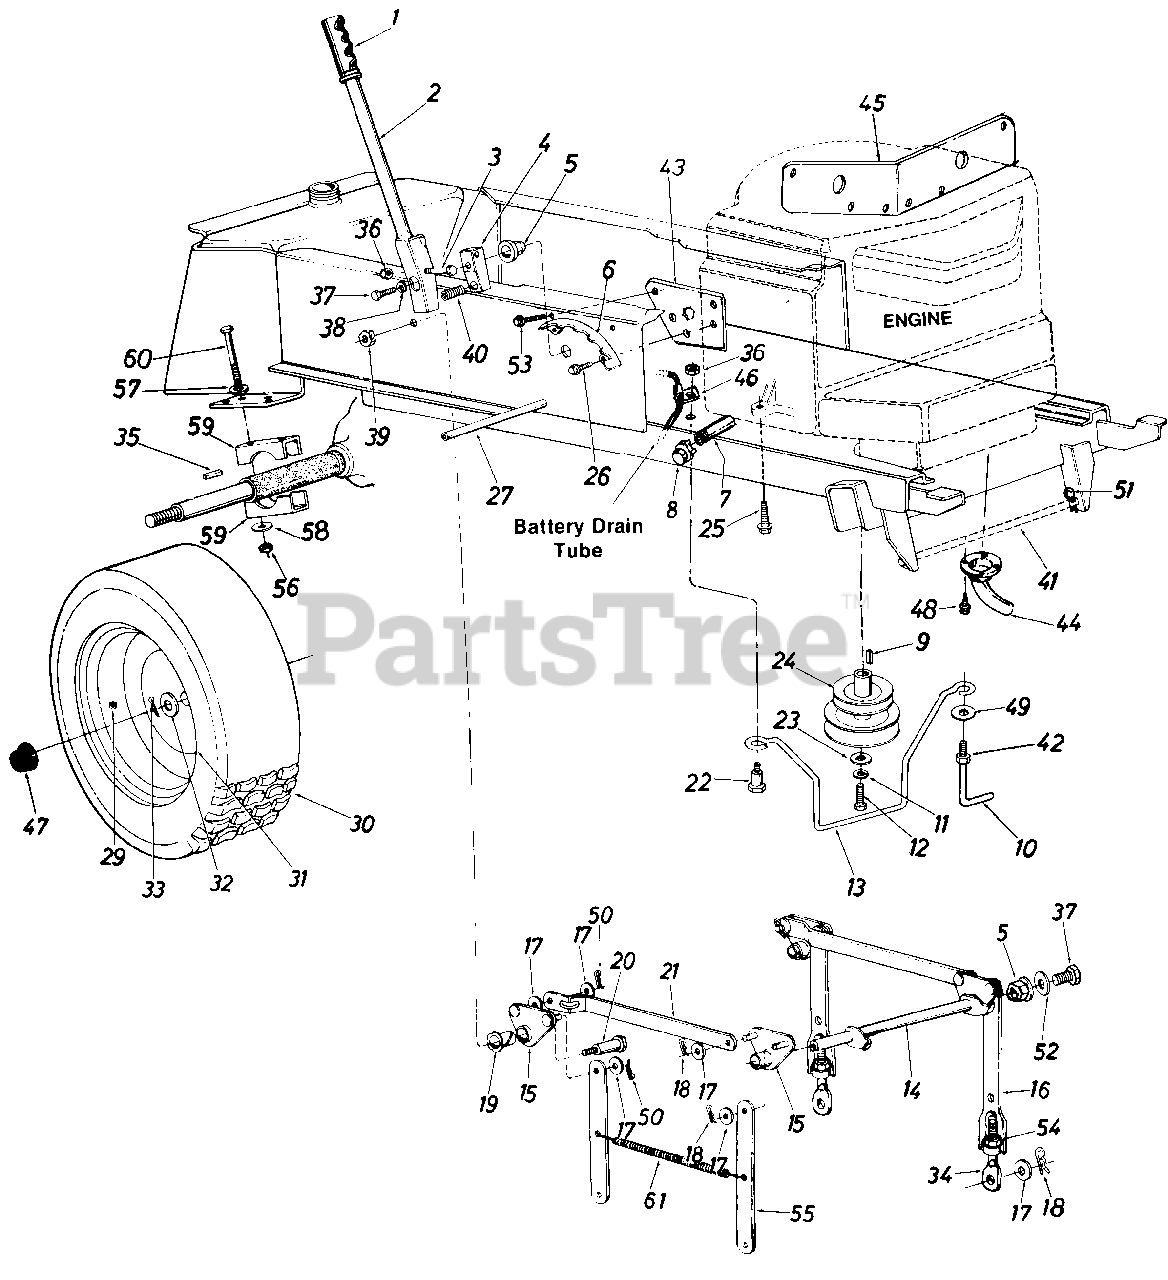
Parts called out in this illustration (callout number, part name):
1	Grip
2	Lift Handle Ass'y.
3	Hex Scr. 5/16-18 x 1.50" Lg.
4	Lift Shaft Drive
5	Plastic Hex Brg. 5/8" I.D.
8	Pipe Cap 3/8-18 Npt.
9	Sq. Key 1/4" x 1/4" x 1.50" Lg.
10	Belt Guard Lock Pin
11	L-Wash. 7/16" Scr.
12	Hex Scr. 7/16-20 x 1.50" Lg.
13	Belt Guard
14	Lift Shaft Ass'y.
15	Lift Pivot Brk't. Ass'y.
16	Adj. Deck Lift Link
17	Fl-Wash. 112" I.D. x 1.00" O.D. x .090
18	Hairpin Cotter
19	Nyliner 5/8" I.D. x .88" Lg.
20	Shld. Scr. 5/8" Dia. x .96" Lg. 3/8-16
23	Flat Wash. .44" I.D. x 1.25" O.D. x .17
24	Two-Step Engine Pulley 4 75 & 5.56
25	Hex Wash. Hd. Scr. 3/8-16 x 1.25" Lg.
26	Hex Thd. Rolling Scr. 5/16-24 x .75" Lg.
27	Running Board Rod
29	Air Valve
33	Cotter Pin 3/16" Dia. x 1.50" Lg.
34	Eye Bolt Adj. Link 1/2-13 Thd.
35	Sq. Key 1/4 x 3.0"
36	Hex Cent. L-Nut 5/16-18 Thd.
37	Hex Scr. 5/16-24 x .62" Lg.
38	L-Wash. 5/16" Scr.
39	Hex Top L-Nut 3/8-16 Thd.
40	Compression Spring
41	Deck Connecting Rod
42	Hex Nut 5/16-24 Thd.
45	Heat Shield
46	Mounting Clamp
47	Hub Cap
48	Hex Wash. Hd. AB-Tap Scr. #10 x .50" Lg.
49	Belle-Wash. .39" I.D.
50	Cotter Pin .09 Dia. x 1.0" Lg.
51	Int. Cotter Pin
52	Fl Wash. .34" I.D. x 1.12" O.D. x .125
53	Hex Wash. Hd. AB-Tap Scr. 5/16 x .50" Lg.
54	Hex Nut 1/2-13 Thd.
56	Hex Nut 3/8-16 Thd.
57	Fl-Wash. .385" I.D. x .87" O.D.
58	Bell-Wash. .39" I.D. x 1.13" O.D.
59	RearAxle Bracket
60	Hex Bolt 3/8-16 x 3.5" Lg.
61	Extension Spring 81/4" Lg.
